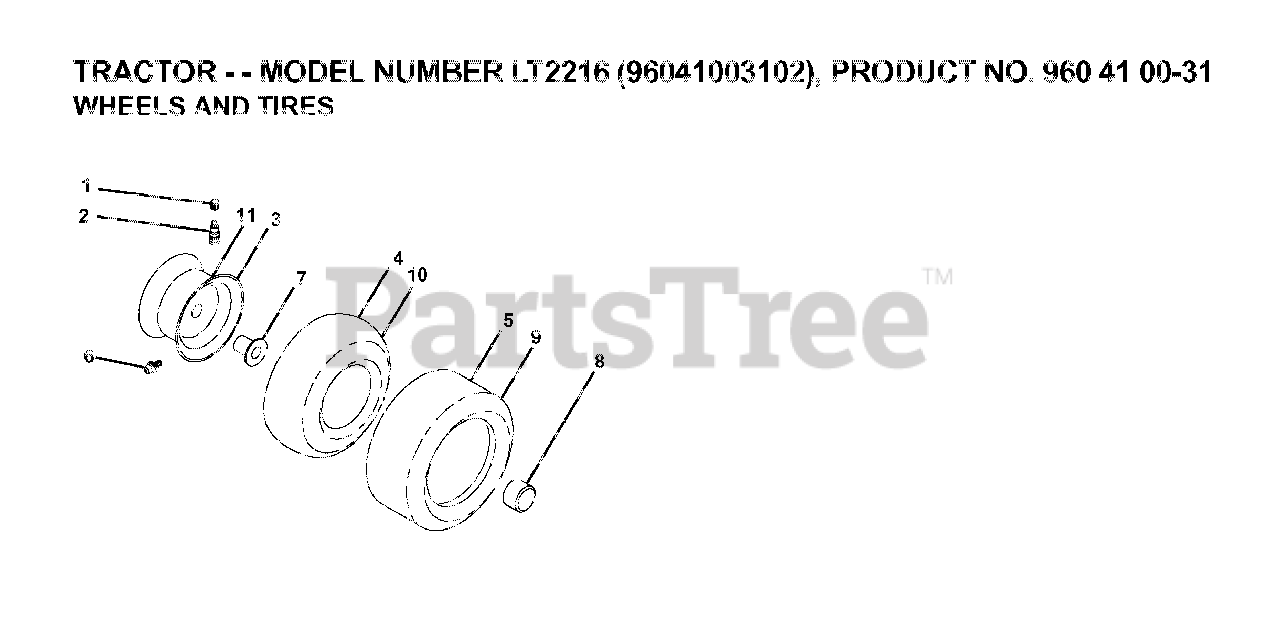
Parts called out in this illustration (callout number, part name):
1	VALVE CAP
2	VALVE STEM LT
3	RIM ASM 6" FRONT SILVER
4	TUBE.5.3/4.5/6
5	TIRE HEAVY DUTY
6	FITTING LT
7	BEARING T
8	CAP, AXLE BLK
9	TIRE HEAVY DUTY
10	TUBE
11	RIM ASM 8" REAR SILVER
